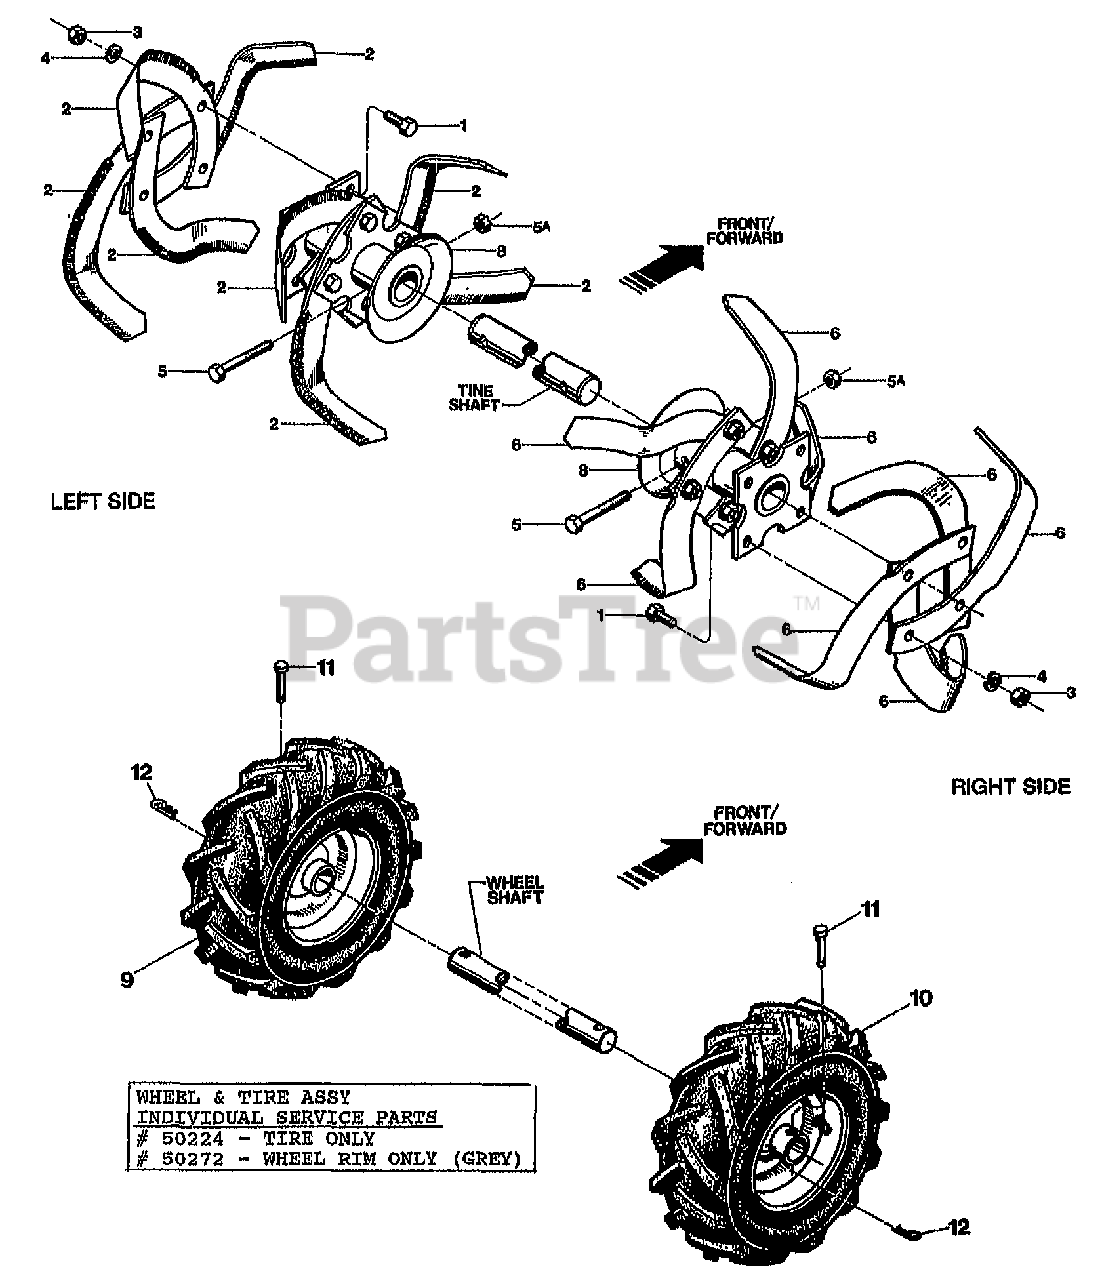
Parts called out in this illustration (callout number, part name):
1	SCR-HH 3/8-16X1.0 G5 ZP
2	TINE-BOLO RIGHT
3	NUT-HEX 3/8-16 ZP
4	WASHER-LK .375 @ DEPL
5	SCR-HH 3/8-16X2.00 G8
5A	NUT-H/LK 3/8-16
6	TINE-BOLO LEFT
8	HOLDER-TINE JUNIOR
9	ASSM-WHEEL&TIRE LT
10	ASSM-WHEEL&TIRE
11	PIN-CLEVIS
12	PIN-HITCH ZP
